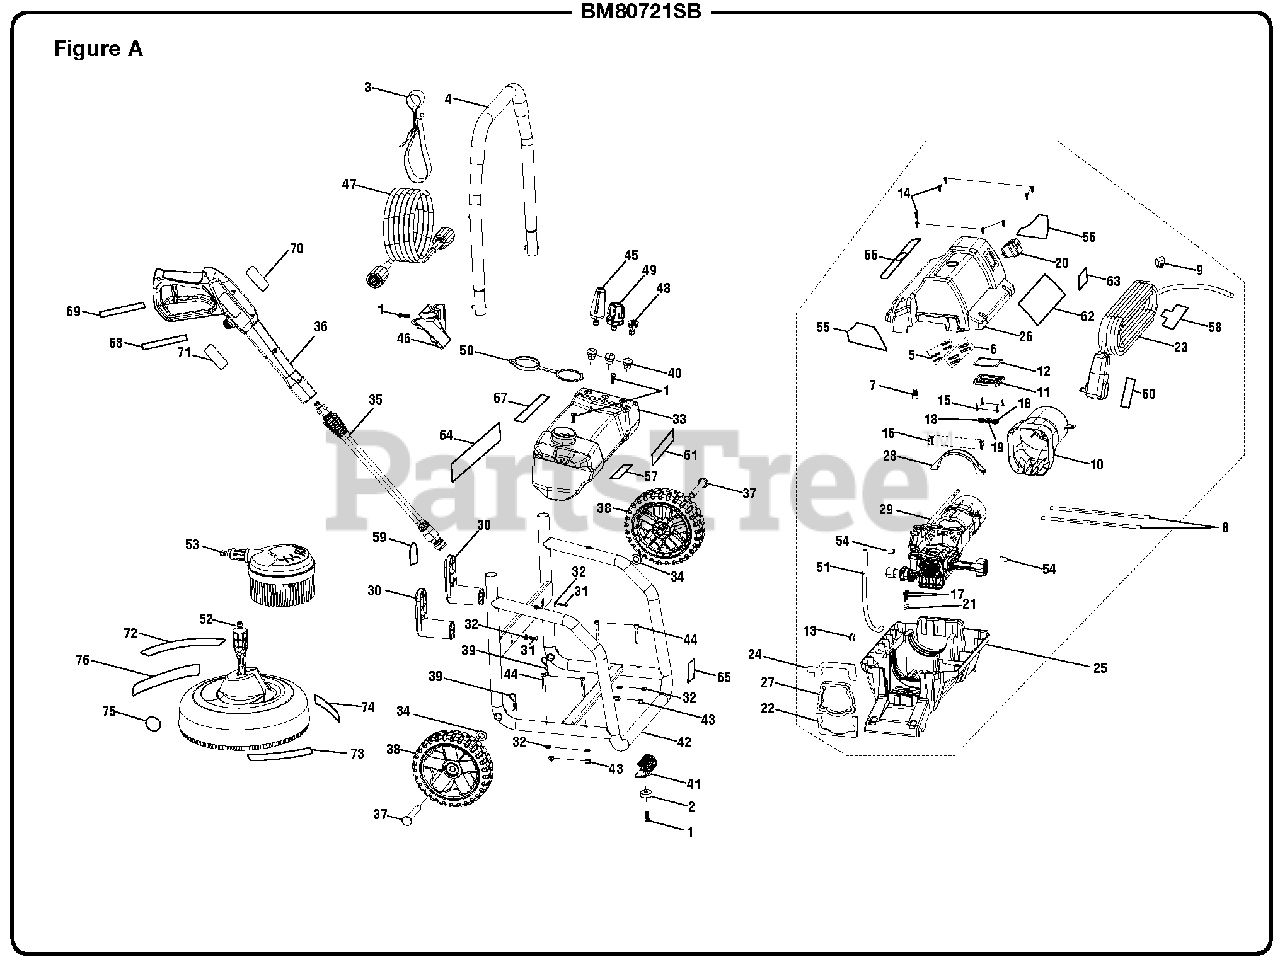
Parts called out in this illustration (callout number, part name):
1	Bolt (M6 x 20 mm)
2	Rubber Foot
3	Hose Storage Strap
4	Handle Assembly
5	Terminal Connector
6	Plastic Sleeve
8	Thermal Sleeve
9	Cord Clip
10	Air Shroud
11	Switch Cover
12	Switch Cover Gasket
13	Grommet (Housing)
14	Screw (M4.2 x 15 mm, Pan Hd.)
15	Screw (M2.9 x 14 mm, L.H.)
16	Screw (M4.2 x 16 mm, Washer Hd.)
17	Screw (M3.5 x 20 mm, Button Hd.)
18	Grommet (ID7.2 x OD11)
19	Motor Grommet
20	Main Switch
21	Cord Clamp
23	Power Cord
25	Bottom Housing
26	Top Housing
28	Bracket/Motor Strap
29	Motor and Pump Assembly
30	Cord Wrap Arm
31	Screw (M4.8 x 19 mm, Button Hd.)
32	Washer (M6)
33	Soap Tank
34	Washer (ID12.5 x OD24 x 2t)
35	Spray Wand
36	Trigger Handle
37	Wheel Axle
39	Cotter Pin
40	Nozzle Grommet
41	Plastic Foot
42	Main Frame
43	Lock Nut (M6)
44	Bolt (M6 x 40 mm)
45	Turbo Nozzle
46	Trigger Handle Holder
47	High Pressure Hose
48	15deg Nozzle
49	Soap Blaster Nozzle
50	Detergent Cap
51	Detergent Injection Hose
52	Surface Cleaner Attachment (11 in.)
53	Rotary Brush Attachment
55	Regulatory Danger Label
56	Danger Label
57	Soap Dilution Label
58	Cordwrap Warning Label
59	Cord Unlock Label
60	Cord Plug Label
61	Performance Label
62	Logo Label
63	On/Off Switch Label
64	Quick Start Label
65	Inquiries Label
66	Nozzle Selection Label
67	Detergent Tank Label
68	Trigger Handle Rating Label
69	Trigger Handle Warning Label (French/Spanish)
70	Trigger Handle Warning Label (English)
71	Trigger Handle Logo Label
72	Performance Label
73	Surface Cleaner Danger Label
74	Surface Cleaner Rating Label
75	No Hands Label (Cleaning Deck)
76	Logo Label
